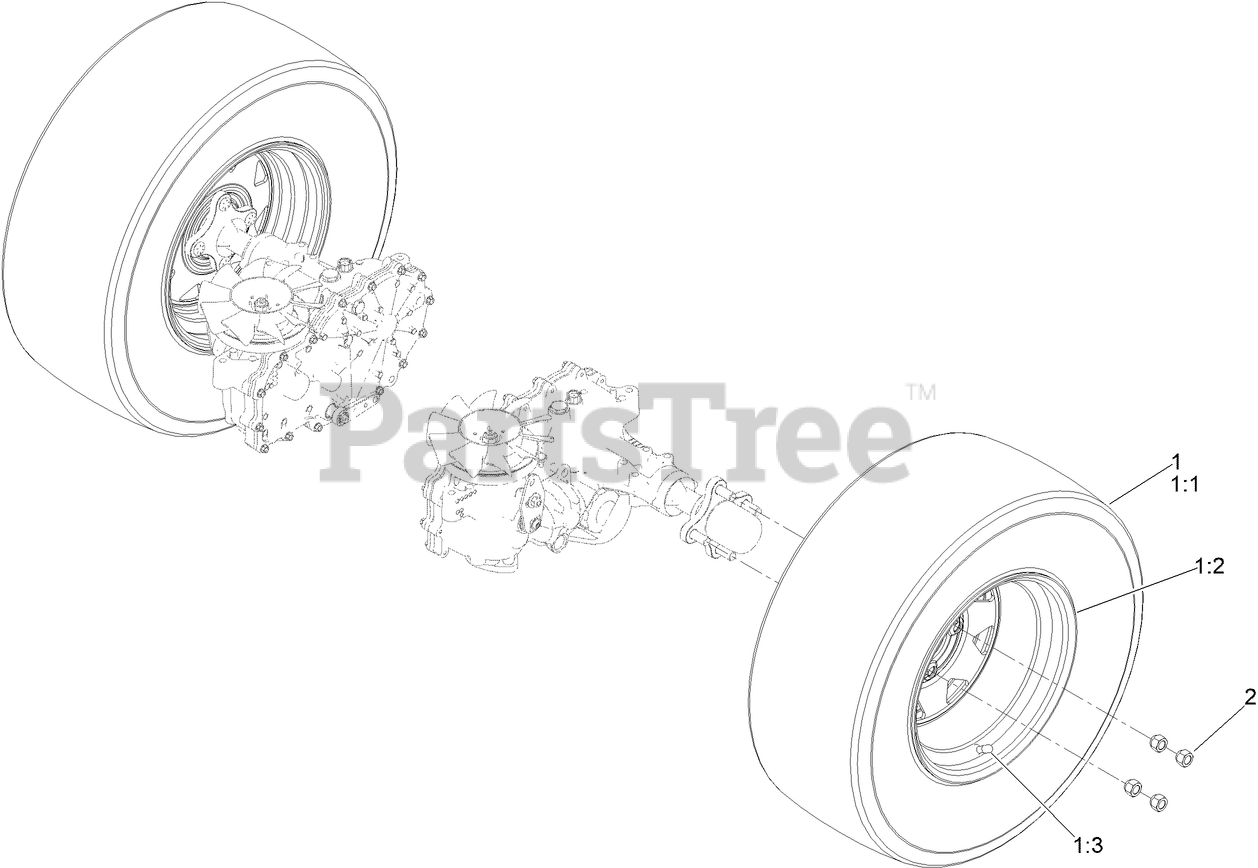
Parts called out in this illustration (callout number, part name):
1	ASM-VOODOO TRAC 24X9.5-12
1:1	TIRE-VOODOO
2	NUT-LUG
